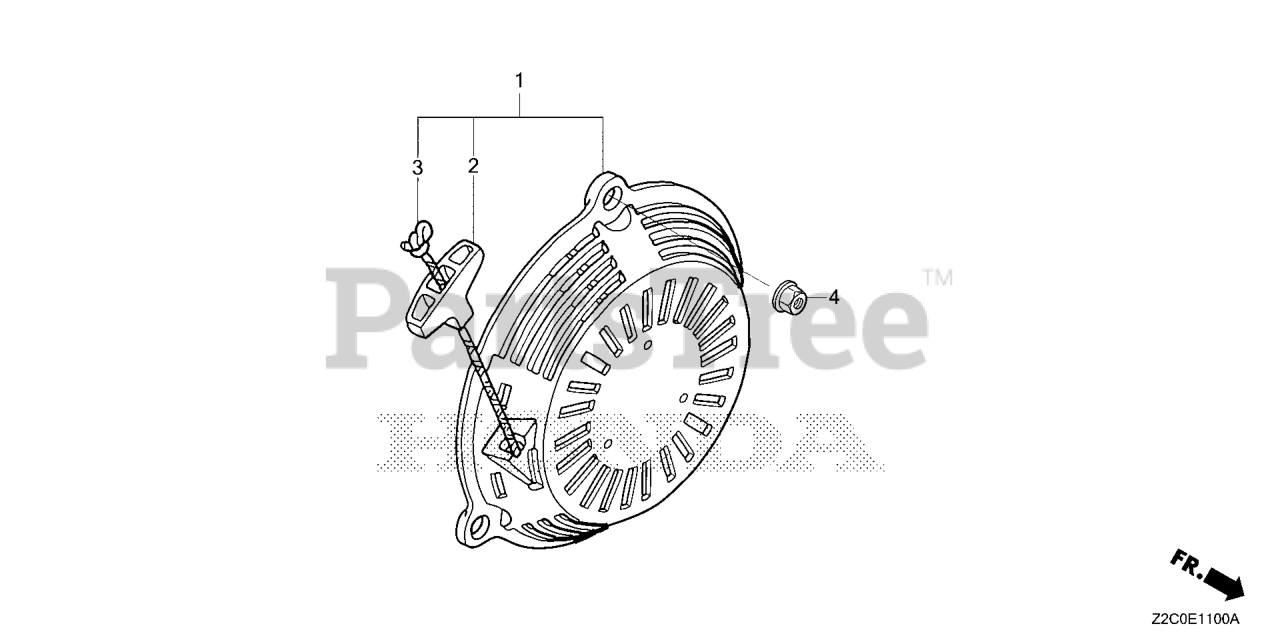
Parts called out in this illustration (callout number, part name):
1	STARTER ASSY., RECOIL *R280* (SHORT ROPE) (POWER RED)
1	STARTER ASSY., RECOIL *NH1* (SHORT ROPE) (BLACK)
2	KNOB, RECOIL STARTER
3	ROPE, RECOIL STARTER (#3.5X52")
4	NUT, FLANGE (6MM)
